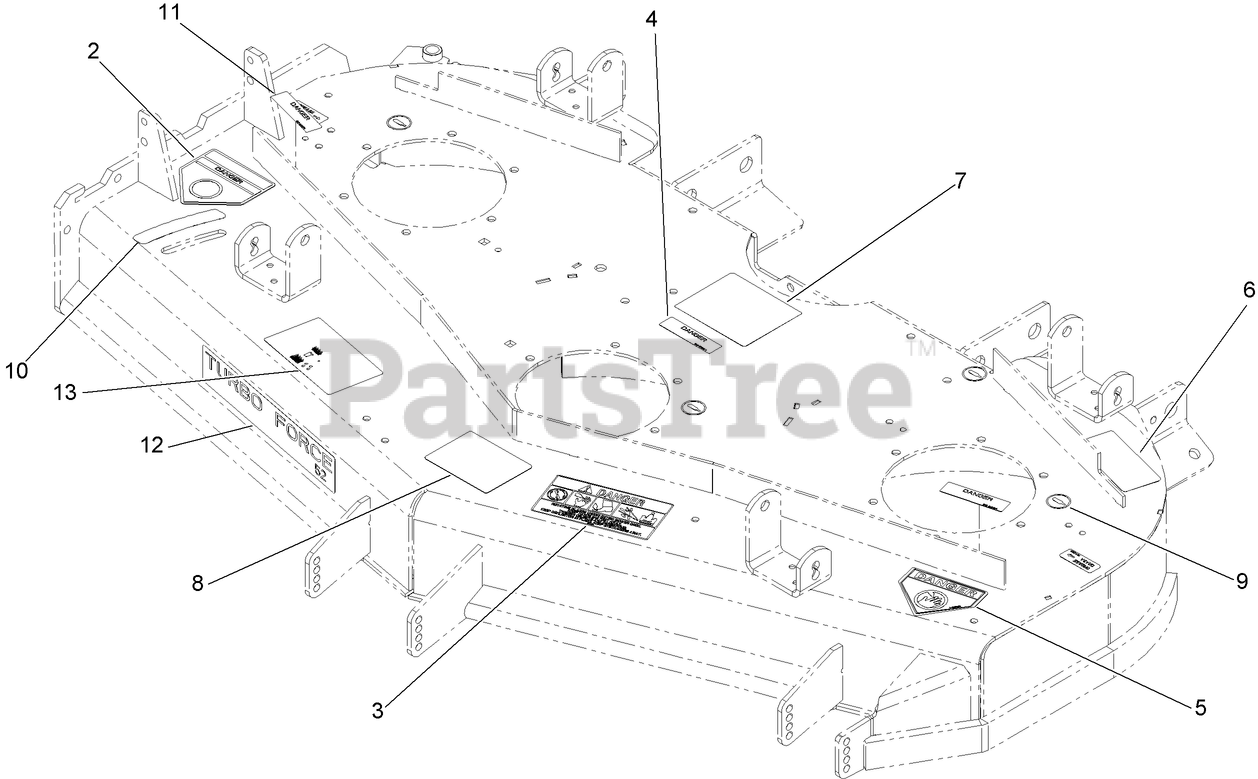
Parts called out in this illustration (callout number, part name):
2	DECAL-DANGER
3	DECAL-DANGER, THROWN OBJECT
4	DECAL-COVER, MISSING
5	DECAL-DANGER
6	DECAL-TORQUE
7	DECAL-ROUTING, BELT
8	DECAL-SCALP, ANTI
9	DECAL-GREASE
10	DECAL-SETTING, BAFFLE
11	Decal-Grease
13	DECAL-ADJUSTMENT, BAFFLE
